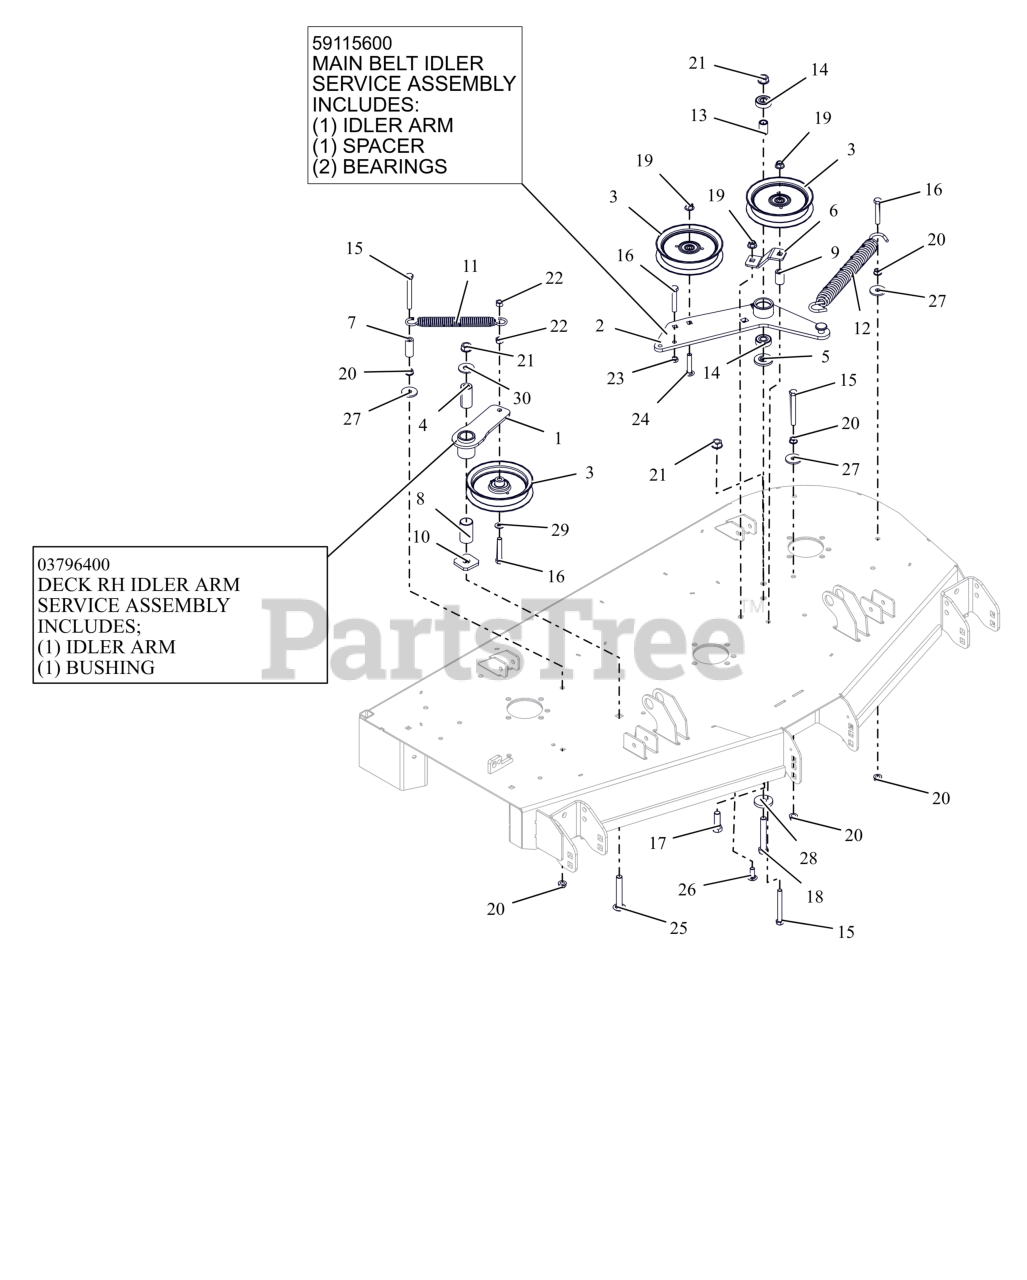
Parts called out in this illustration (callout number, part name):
1	ASM, IDLER ARM (DECK)
2	ASSEMBLY, MAIN BELT IDLER
3	IDLER, FLAT 5.00"
4	BSHG, SPCR .502X.997X2.03 PM
5	SPACER, IDLER ARM
6	PTO FIXED IDLER MTG BRKT -RED
7	HOSE, .38 X 1.65
8	BSHG, 1.00X1.125X1.937
9	BUSHING, SLV .380X.750X1.190
10	WSHR-FLT .640X1.75X.250
11	SPRING, EXTENSION
12	SPRING, EXTENSION
13	SPACER .510 X .75 X 1.1485
14	BRG-BALL .500X1.38X.437
15	BLT, HEX .38-16X3.25 G5 ZCC
16	BLT,HEX .38-16X2.25 G5 ZCC
17	BLT,HEX .50-13X1.50 G5 ZCC
18	BLT,HEX .50-13X3.25 G5 ZCC
19	NUT,NYL-FLG .38-16 GF ZCC
20	NUT, SPNLK-FLG .38-16 G5 ZCC
21	NUT-LK-CTR-FLG .500-13 GG ZCC
22	NUT-LK-CTR .38-16 ZC120
23	NUT-JAM .375-16 G2 ZCC
24	BLT,RHSSN.375-16X2.00 G5 ZCC
25	BTL,RHSSN .500-13 X 3.25 G5 ZCC
26	BLT,RHSSN .38-16X1.00 G5 ZCC
27	WSHR,FLT .406X1.375X.135 ZCC
28	WSHR-FL-STL 0.557X1.625X0.25 ZCC
29	WSHR,FLT .406X.812X.065 ZCC
30	WSHR,FLT .563X1.375X.109 ZCC
